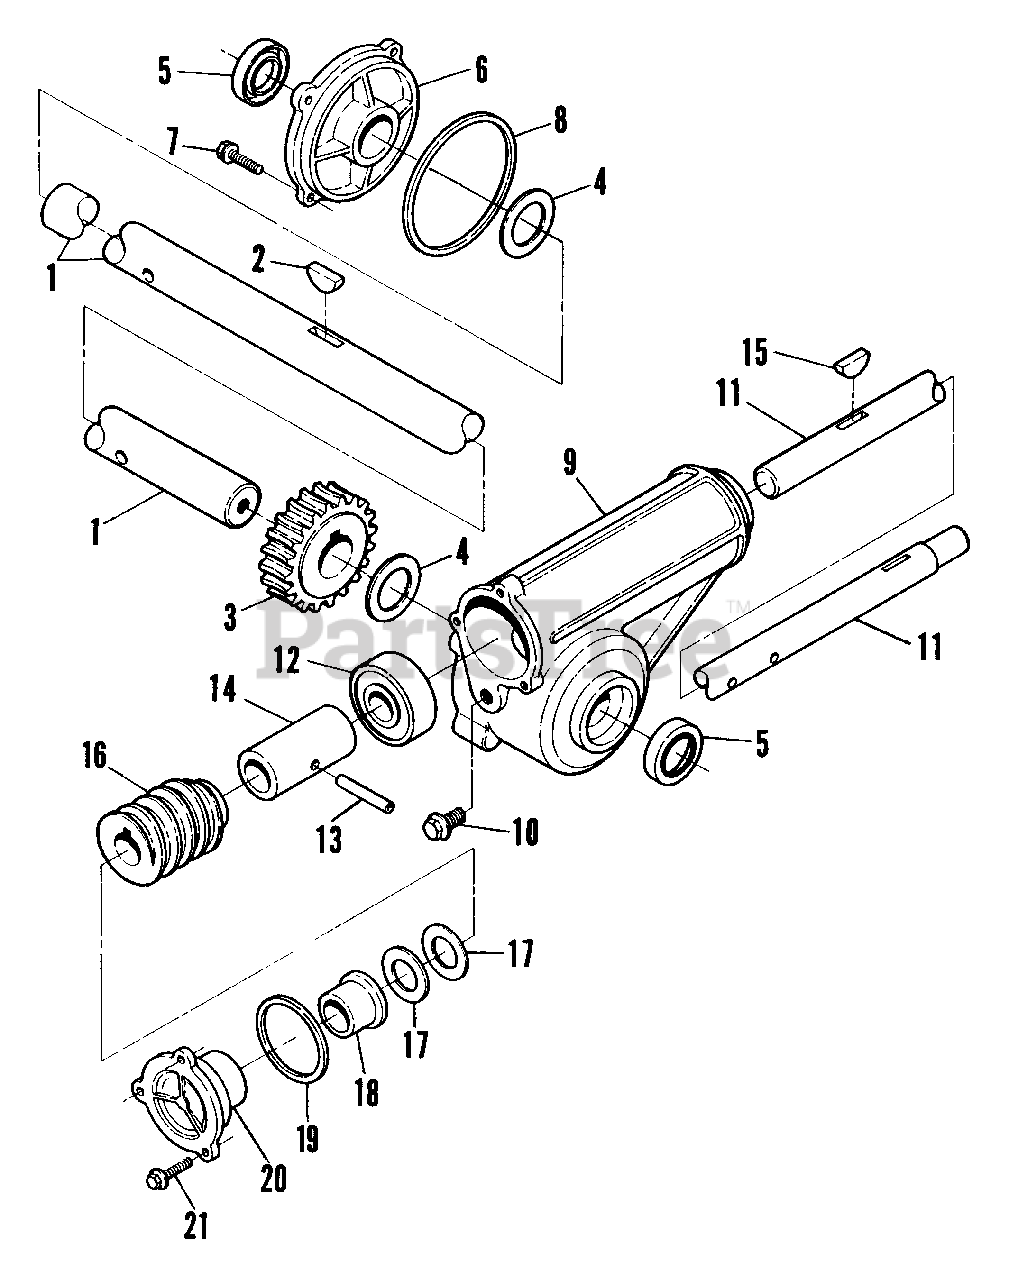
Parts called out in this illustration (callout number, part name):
1	SHAFT, Auger
2	KEY, Woodruff
3	GEAR, Worm
4	WASHER, Thrust
5	SEAL, Oil
6	COVER, Gear Case
7	SCREW, 1/4 - 20 x 3/4 Self Tap
8	O-RING (Case Cover)
9	CASE, Gear
10	PLUG, Check (3/8 x 1/2 Self Tap Screw)
11	SHAFT, Impeller Fan
12	BEARING, Ball
13	PIN, 1/4 x 1-1/2" Roll
15	KEY, 3/16 x 7/8" Woodruff
16	GEAR, Rolled Worm
17	WASHER (Spacers)
18	BUSHING
19	O-RING (End Cap)
20	CAP, End
21	SCREW, 10 - 24 x 5/8 Self Tap
